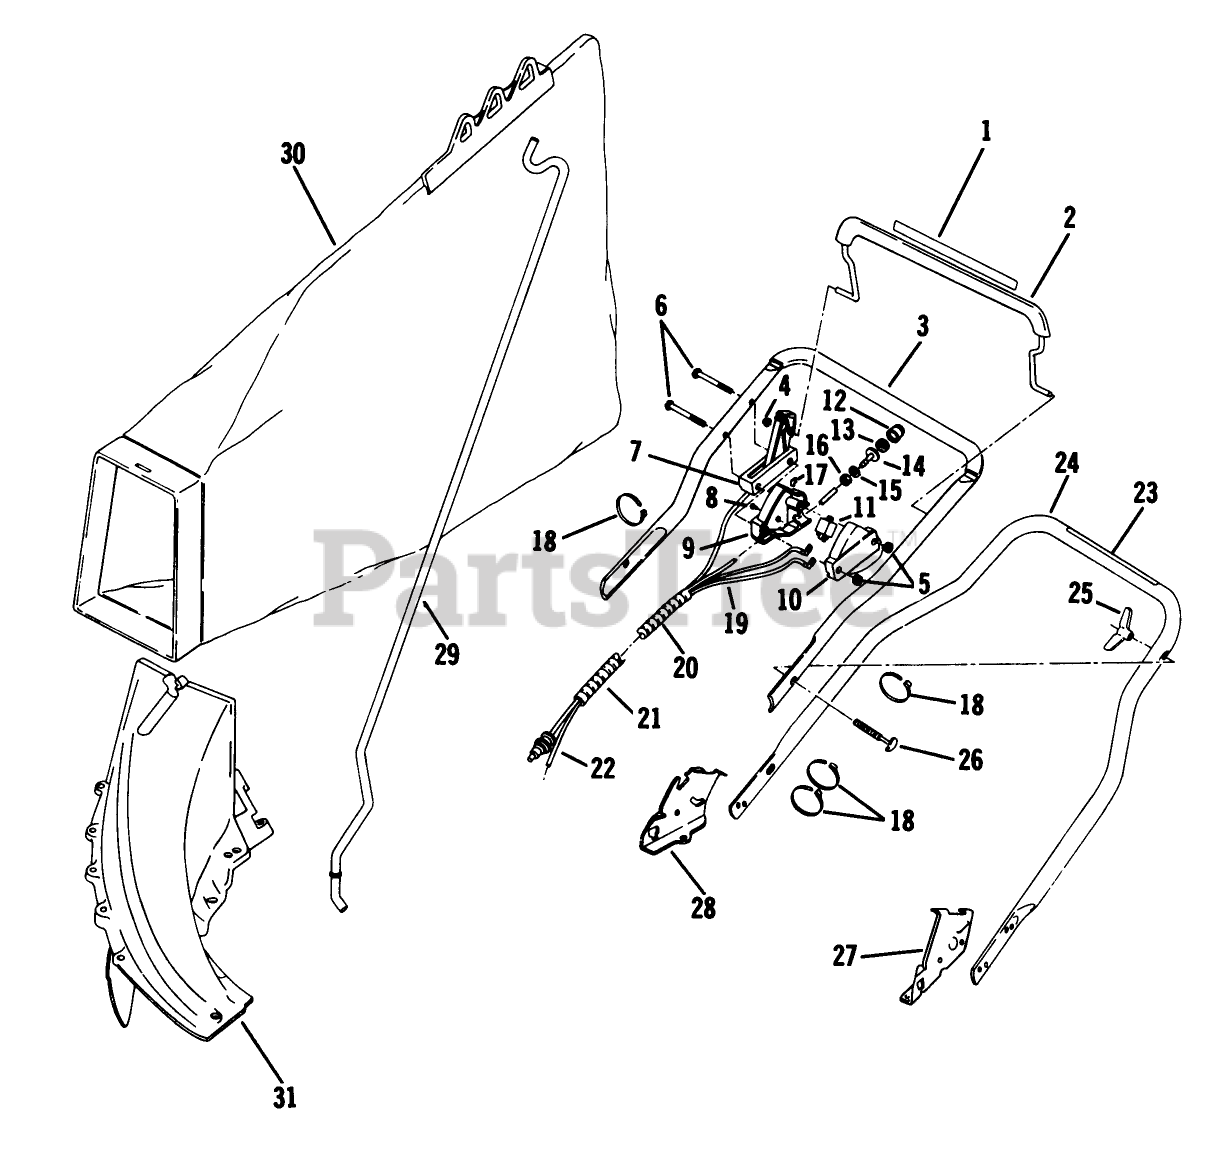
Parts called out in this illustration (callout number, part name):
5	NUT C/LOCK E
6	SCREW
7	BBC CONTROL SER AY
11	SWITCH AY
13	FILTER S
16	LOCKNUT S
25	NUT-WING
26	BOLT QUALITY
29	ROD GRASSBAG
30	89802 LB WHOLE GOODS
